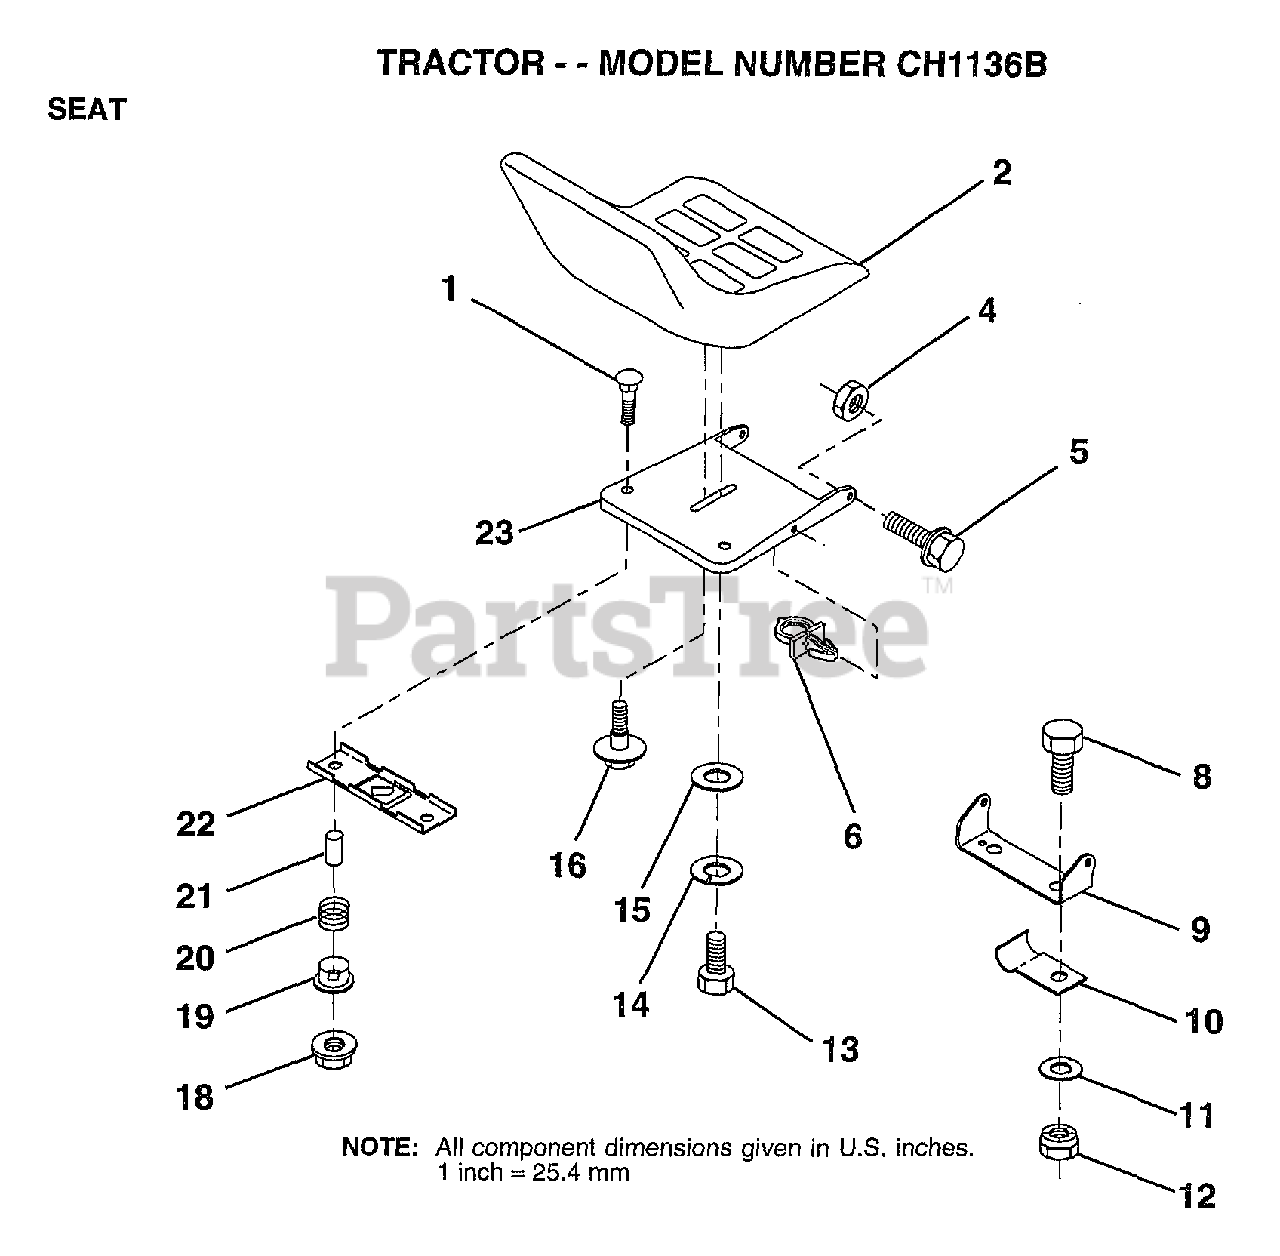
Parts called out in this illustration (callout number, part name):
4	NUT
5	BOLT.SHLD.5/16-18
6	CLIP.PUSH-IN.HING
8	BOLT
9	BRACKET PVT SEAT
10	"CLIP,INSULATOR"
11	WASHER
12	NUT
13	BOLT
14	LOCKWASHER
15	WASHER
16	"BOLT,SHOULDER"
19	BUSHING
20	SPRING
21	SPLIT SPACER
22	BRKT SWITCH
